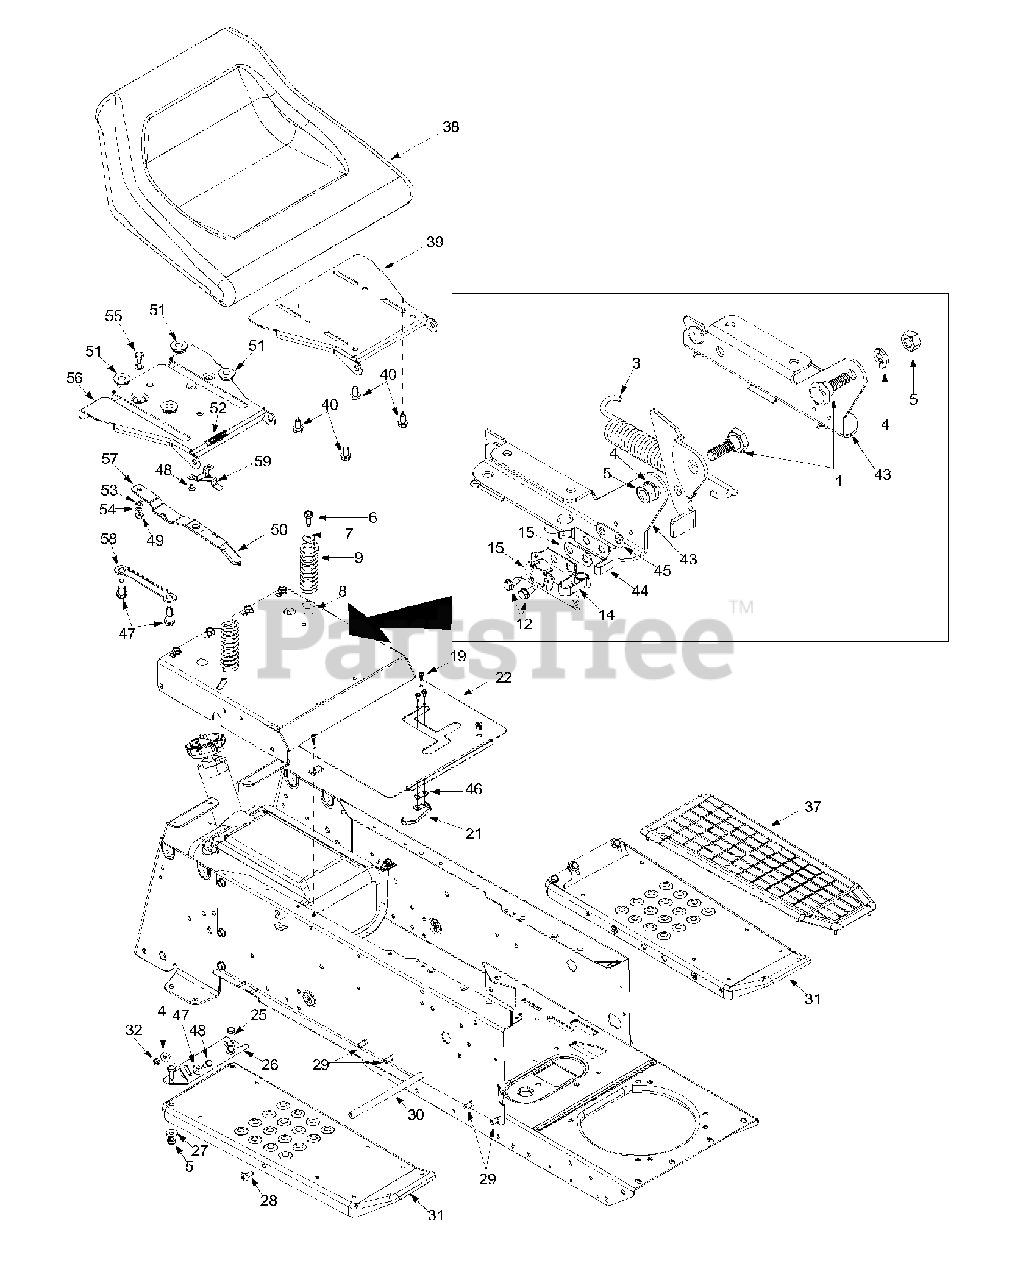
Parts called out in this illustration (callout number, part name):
1	Shld. Bolt .437" Dia. x .162"
3	Ext. Spring 5.31"
4	L-Washer 5/16" I.D.
5	Hex Nut 5/16-18 Thd. (Gr. 5)
6	Hex Wash. Hd. Tap Scr. 5/16 -18 x .7"
7	Flat Washer .344" I.D.
8	Bushing
9	Compression Spring
12	Hx Wash. Hd. AB-Tap Scr. #8 x .5"
14	Spring Switch
15	Insulator Plate
19	Truss Mach. B-Tap Scr.
21	Reverse Safety Switch
25	Hex Bolt 5/16-18 x .75"
28	Truss Mach. Scr. 5/16-18 x .75"
29	Rib Neck Bolt 5/16-24 x .75"
30	Running Board Rod
38	Seat 8-7/8" High
40	Hex Tap Scr. 3/8-16 x .62"
43	Seat Lift Bracket
44	Seat Spring Switch
45	Insulator Boss Plate
46	Insulator Nut Plate
47	Hex Bolt 3/8-16 x 1"
48	Hx Washer B-Tap Scr. #10-16 x .38"
49	Hex Flanged L-Nut 1/4-20 Thd.
50	Seat Adjustable Grip
51	Spacer
52	Compression Spring 1.5"
53	Spring Washer .265" I.D. x .56" O.D.
54	Flat Washer .344" I.D. x .62" O.D.
55	Shld. Bolt .34" x 1/4 -20 Thd.
58	Seat Selector
59	Seat Stop
